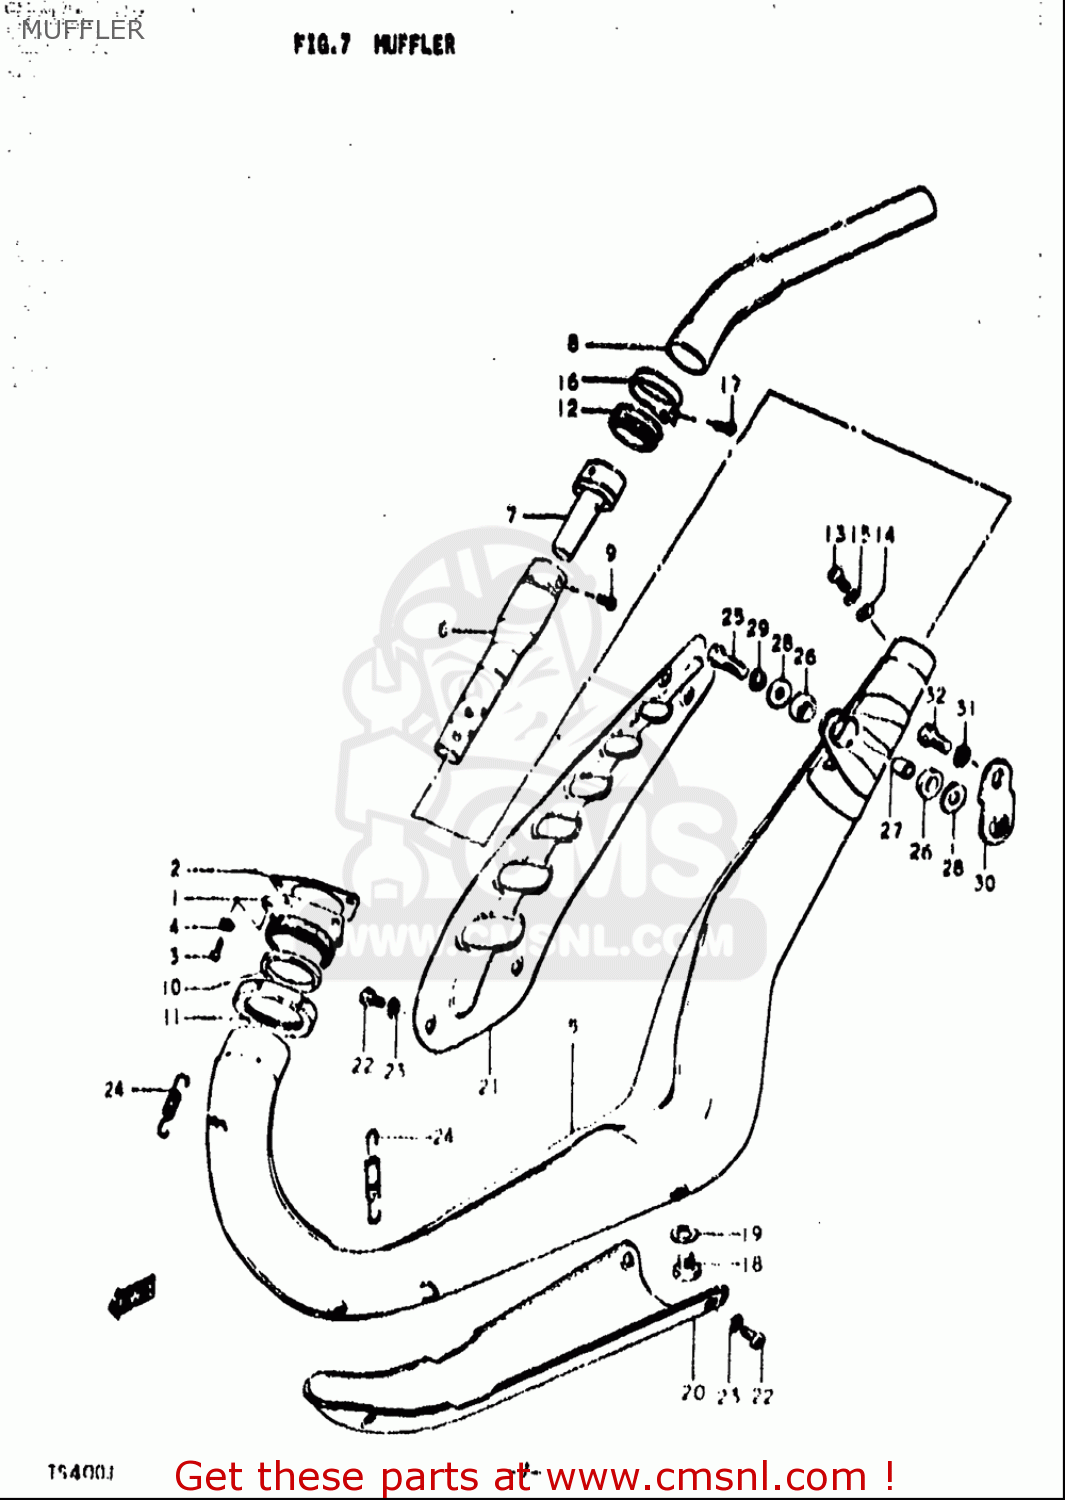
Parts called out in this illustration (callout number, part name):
3	SCREW
4	WASHER,LOCK
9	SCREW
10	CLAMP,EXHAUST PIPE
13	SCREW
14	GASKET
15	WASHER,LOCK
16	CLAMP
17	SCREW
18	PLUG
19	GASKET(10X14X3.6) (NAS)
22	SCREW
23	WASHER,LOCK
24	SPRING
25	BOLT
27	SPACER (8.2X12.5X23.5)
28	WASHER(8.5X22X2)
29	WASHER,LOCK
31	WASHER,LOCK
32	BOLT(8X14)
